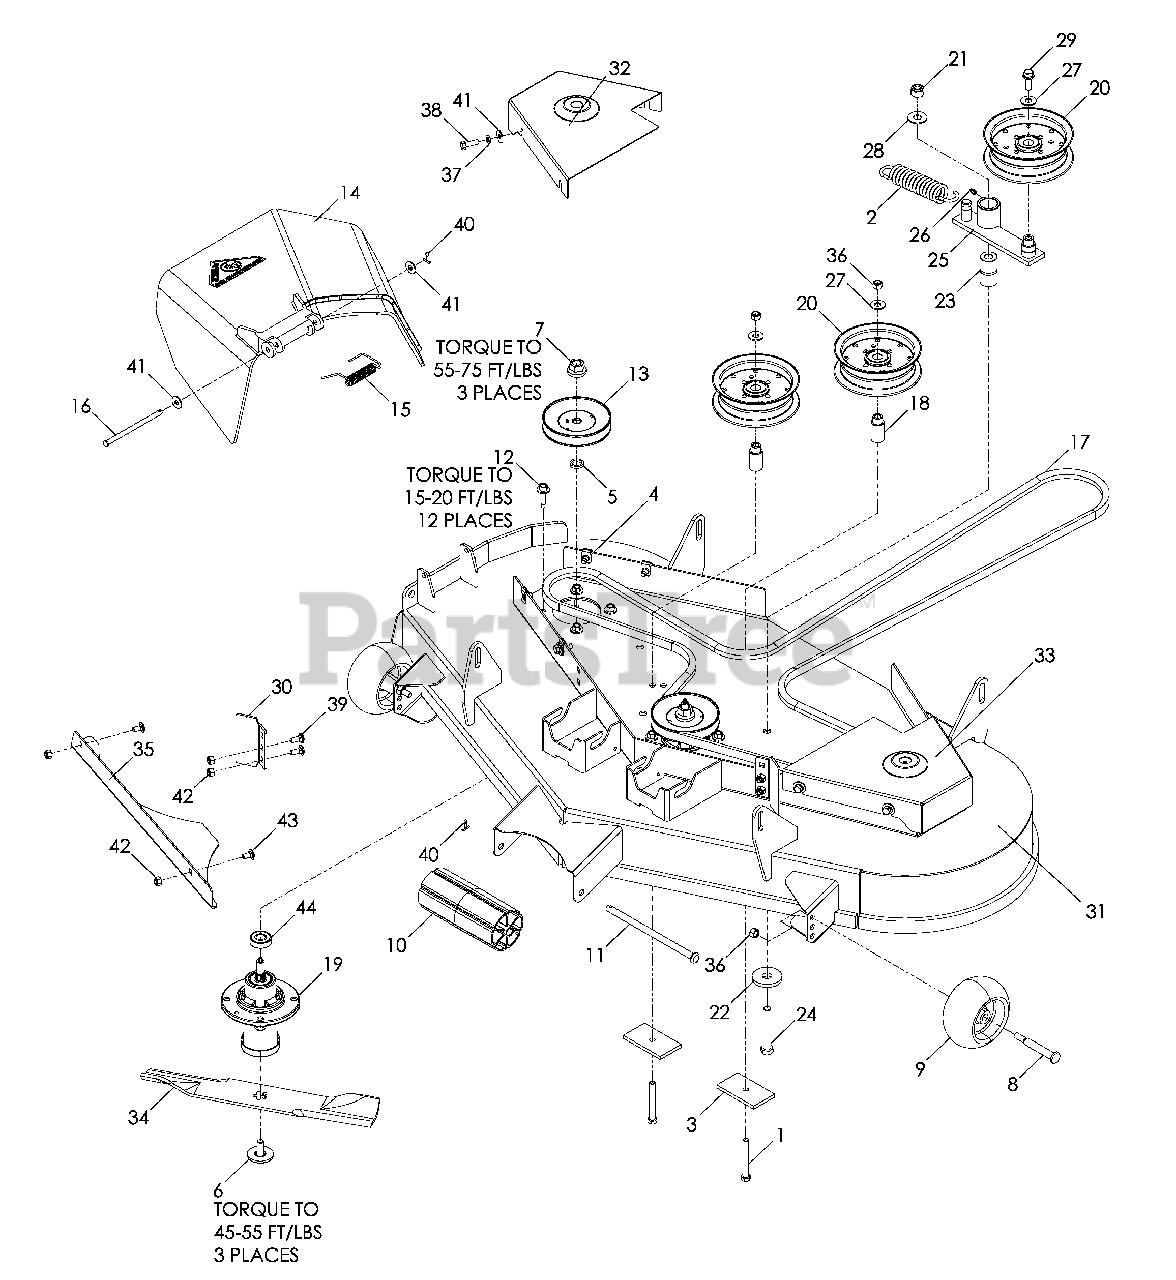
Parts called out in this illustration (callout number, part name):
1	HCS 3/8-16 x 3
2	SPRING, EXTENSION
3	PAD
4	NUT 5/16-18 RETAINER-U
5	WASHER, SPACER
6	BOLT 7/16
7	NUT 9/16 TOP CNTRLOCK
8	SB ½ x 25/8
9	WHEEL, GAUGE
10	ROLLER, NOSE
11	ROD, ROLLER, NARROW
12	SCREW 5/16-18 x 13/8 WSH HD
13	PULLEY, MANDREL
14	CHUTE, DISCHARGE
15	SPRING, TORSION
16	PIN, CLEVIS 5/16 DIA x 5.19
17	DECK BELT
18	BUSHING, IDLER
19	HOUSING ASSEMBLY
20	PULLEY, IDLER
21	NUT ½-13 NYLOC
22	WASHER .65 SUPPORT
23	BUSHING, PIVOT
24	HCS ½-13 x 3¼
25	ARM, IDLER
26	ZERK, STRAIGHT ¼-28
27	WASHER 3/8
28	WASHER 9/16
29	HCS 3/8-16 x 1 WHIZLK
31	48" DECK W/DECALS
32	BELT SHIELD W/DECAL, RT
33	BELT SHIELD W/DECAL, LT
34	BLADE, 16¼"
35	PLATE, CONFINEMENT
36	NUT 3/8-16 NYLOC
37	LOCKWASHER 5/16
38	HCS 5/16-18 x 1
39	RHSNB 5/16-18 x ¾
40	PIN, COTTER 1/8 x ¾
41	WASHER 5/16
42	NUT 5/16-18 NYLOC
43	RHSNB 5/16-18 x 5/8
44	BEARING, BALL
